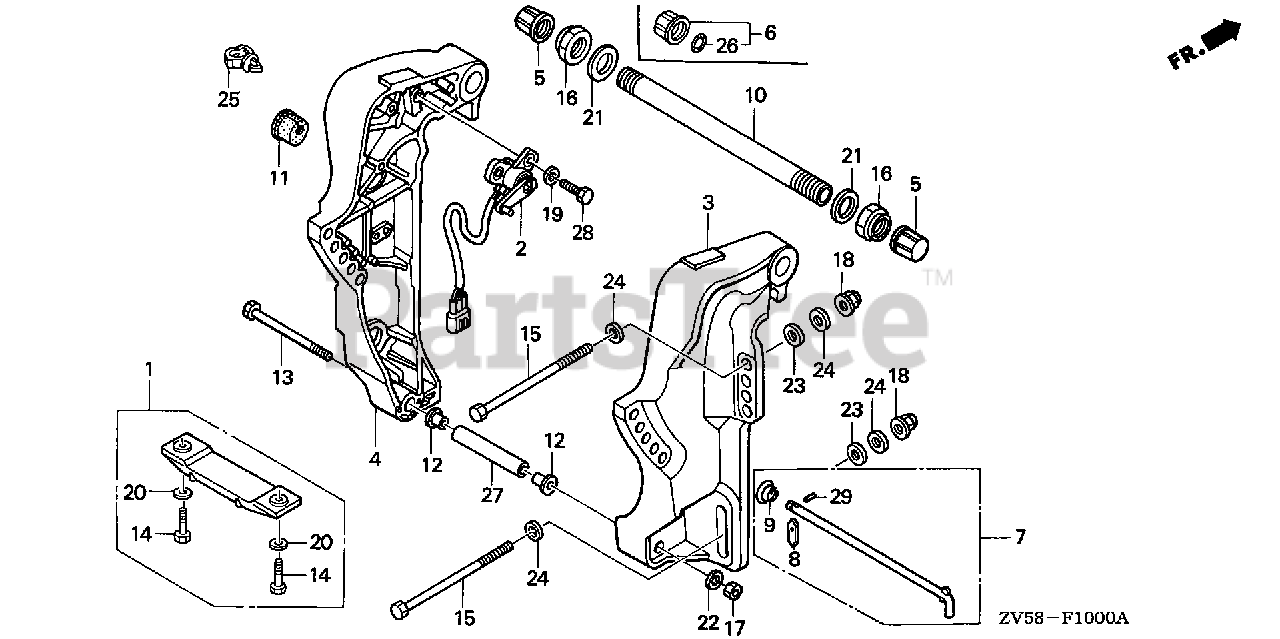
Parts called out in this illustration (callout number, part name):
1	METAL KIT, ANODE
2	SENSOR ASSY., TRIM ANGLE
3	BRACKET, R. STERN *NH282MU* (OYSTER SILVER METALLIC-U)
4	BRACKET, L. STERN *NH282MU* (OYSTER SILVER METALLIC-U)
5	CAP, TILTING BOLT
7	ROD, ADJUSTING
8	STOPPER, ROD
9	SPRING, ADJUSTING ROD
10	SHAFT, TILTING
11	BUSH, MOTOR CODE
12	BUSH, CYLINDER (LOWER)
13	BOLT, HEX. (10X158)
14	BOLT, HEX. (6X25) Use up to Frame SN 4800342.
15	BOLT, HEX. (12X100)
16	NUT, SELF-LOCK (7/8-14UNF)
17	NUT, SELF-LOCK (10MM)
18	NUT, SELF-LOCK (12MM)
19	WASHER, PLAIN (6MM) Use from Frame SN 4800713.
20	WASHER, PLAIN (6MM) Use up to Frame SN 4800342.
21	WASHER, WAVE (22MM)
22	WASHER, PLAIN (10MM)
23	WASHER, PLAIN (12MM)
24	WASHER, PLAIN (12MM)
25	CLIP, WIRE HARNESS
26	O-RING (15.54X2.26)
27	COLLAR, DISTANCE (10X90)
28	BOLT, HEX. (6X20)
29	PIN, SPRING (2.5X8)
